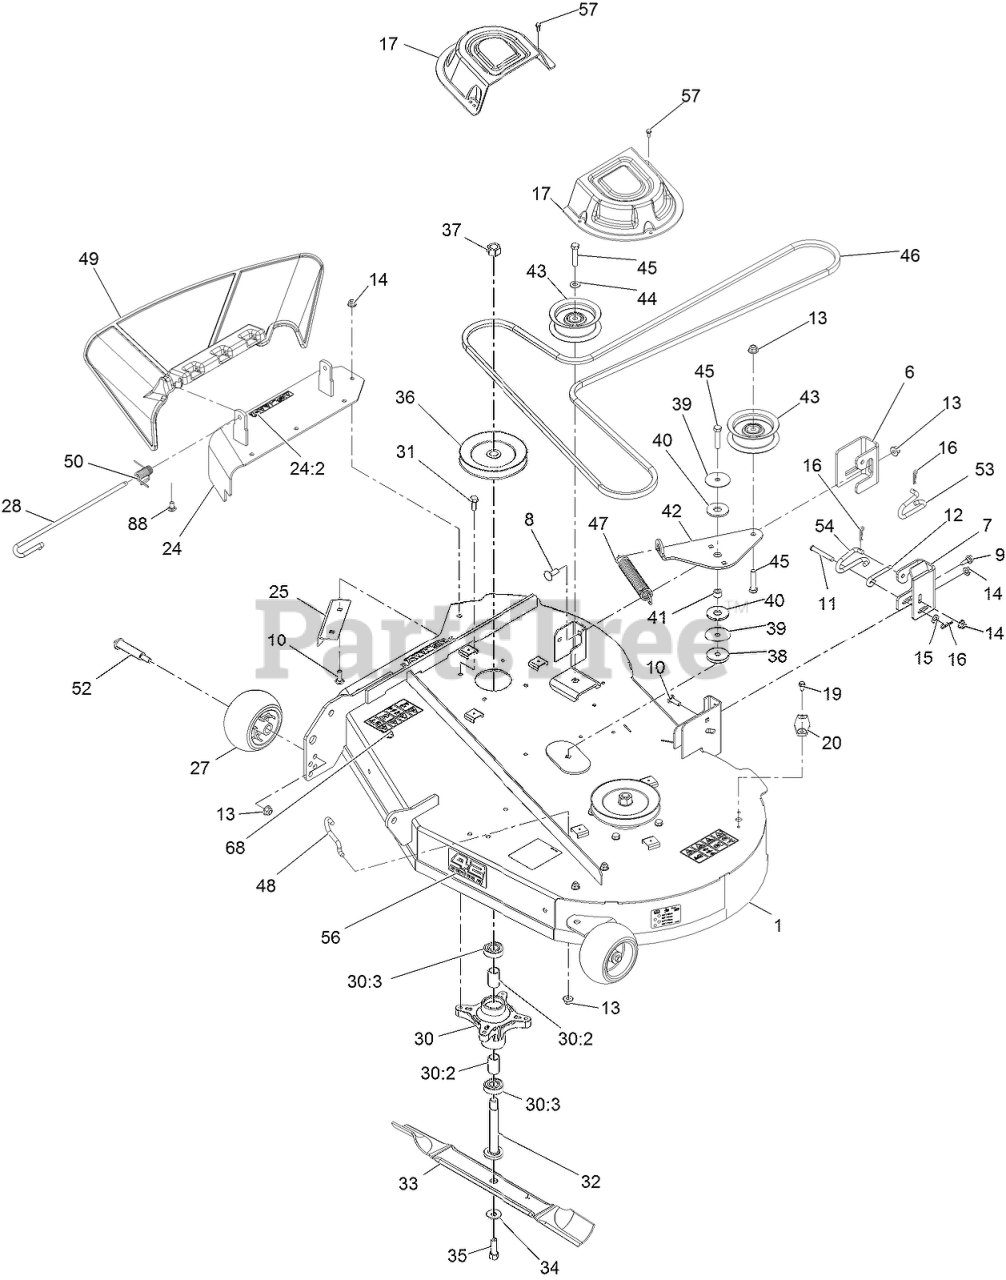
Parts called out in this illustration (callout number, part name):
1	DECK-42 W/DECALS
6	Bracket-Hanger, Right Rear
7	Bracket-Hanger, Left Rear
8	BOLT-CARR
9	SCREW-SHOULDER,HWH
10	SCREW-CARR
11	PIN-CLEVIS
12	Rod-Level, Deck
13	NUT-HF, NI
14	NUT-HF, NI
15	WASHER-PLAIN
16	PIN-COTTER
17	COVER-BELT
19	SCREW-HWH
20	COVER-WASHOUT PORT
24	COVER ASM W/DECAL
24:2	DECAL-DANGER
25	BAFFLE-CUTOFF
27	ROLLER-SCALP, ANTI
28	PIN-CHUTE
30	SPINDLE ASM
30:3	BEARING-BALL
31	SCREW-TAPTITE
32	SHAFT-SPINDLE
33	BLADE-HIGH LIFT
34	WASHER-BELLEVILLE
35	SCREW-HH
37	NUT-HEX
38	WASHER-PLAIN
40	WASHER-FRICTION, COMPOSIT
42	Arm-Idler
43	PULLEY-IDLER, FLAT
44	WASHER-FLAT
45	SCREW-HH
46	V-BELT
47	SPRING EXTENSION
48	Hook-Return Spring
49	DEFLECTOR-DISCHARGE
50	SPRING-TORSION
52	BOLT-SHOULDER
53	LINK-RETENTION, DECK (RH)
54	LINK-RETENTION, DECK (LH)
56	Decal, 42 Series 2
57	SCREW-TAPTITE
68	SCREW-HH
88	SCREW-CARR
